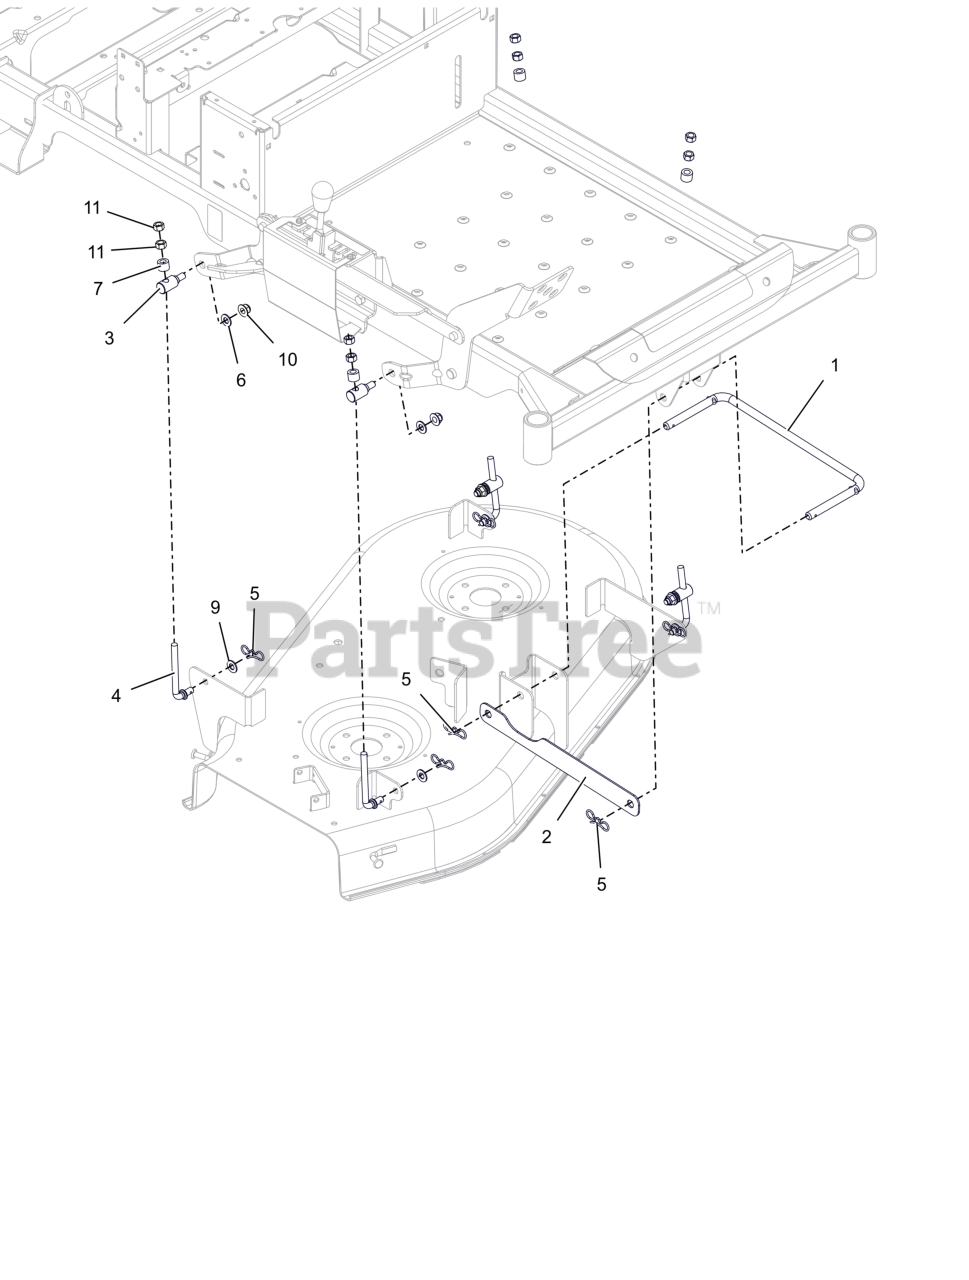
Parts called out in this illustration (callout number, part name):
1	WIREFORM, DRAG LINK
2	STRAP, DRAG LINK
3	TRUNNION, DECK ADJUSTER
4	WIREFORM, DECK ADJUSTMENT
5	PIN, BOWTIE .091X1.875 ZCC
6	WSHR,FLT .406X.812X.065 ZCC
7	BSHG-SLV .407X.625X.750 PL
9	WSHR,FLT .406X.812X.065 ZCC
10	NUT,NYL-FLG .38-16 GF ZCC
11	NUT-STD .375-16 G2 ZCC
